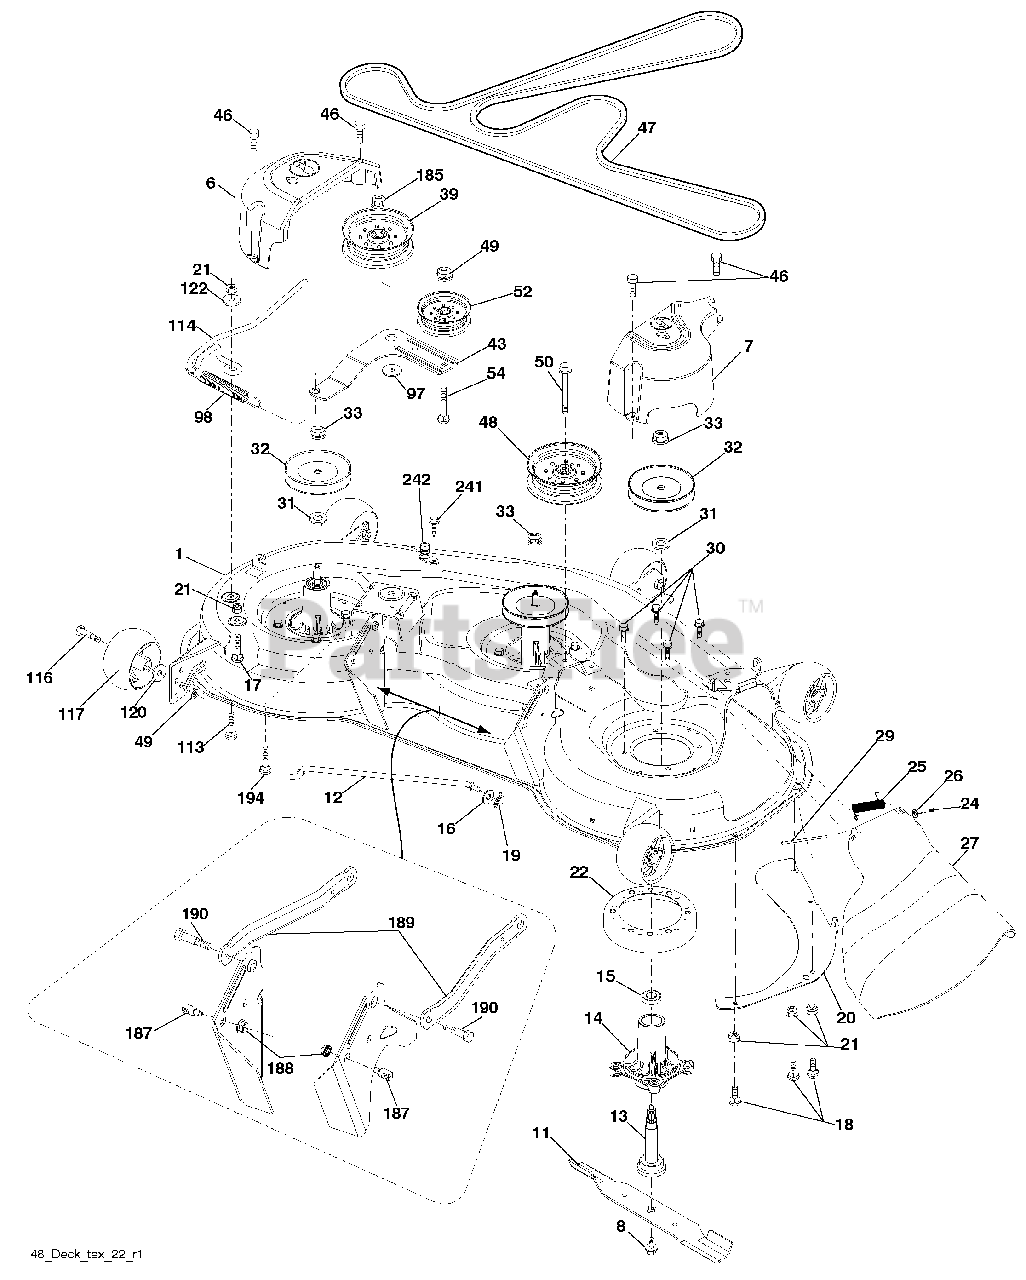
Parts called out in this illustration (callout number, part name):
1	Deck Weldment Mower
6	Cover Mandrel LH
7	Cover Mandrel RH
8	Bolt 7/16 Asm. Blade
11	Blade High Lift
12	Rod Anti-Sway
13	Shaft Asm. w/Lower Bearing
14	Housing, Mandrel
15	Bearing, Ball, Mandrel
16	Washer 13/32 x 13/16 x 12 Ga.
17	Bolt 5/16-18 x 5/8
18	Bolt RdHd 5/16-18 unc x 5/8
19	Pin Cotter 5/16 Bow Tie Lock
20	Baffle Vortex
21	Nut, Crownlock 5/16-18 unc
22	Stripper Mandrel
24	Cap Sleeve
25	Spring, Torsion
27	Deflector Shield
29	Rod, Hinge
30	Screw, Thdroll Washer Head
31	Washer, Spacer Mower Vented
32	Pulley, Mandrel
33	Nut, Flg. Top Lock
39	Pulley, Idler, 4.50 Hub
43	Arm, Idler
46	Screw, Thdroll. 1/4-20 x 5/8
47	Belt Deck Drive
48	Pulley Idler 4.50 RAW
49	Nut, Lock Flg. 3/8-16 unc
50	Screw TT 3/8-16 x 2-1/4
52	Pulley Idler 48" Primary
54	Bolt Carr. Sh 3/8-16 x 1-1/2 Gr. 5
97	Washer Hardened
98	Spring Drive
113	Bolt Rdhd Sqnk 5/16-18 x 3/4
114	Rod Tension Relief
116	Bolt, Shoulder
117	Gauge Wheel
120	Washer 13/32 x 1-1/4 x 12 Ga.
122	Bushing Tension Relief
185	Nut Lock Flange 7/16-14 Gr. 5
187	Stud Fastener w/"D" Anti-Rotation
188	Nut Lock Hex Flange
189	Arm Susp. Mower Rear
190	Bolt Shoulder
194	Bolt Carr Sqnk 7/16-24 x 2
241	Screw TT #10-32.5 3/8 Flange
242	Port, Washout
